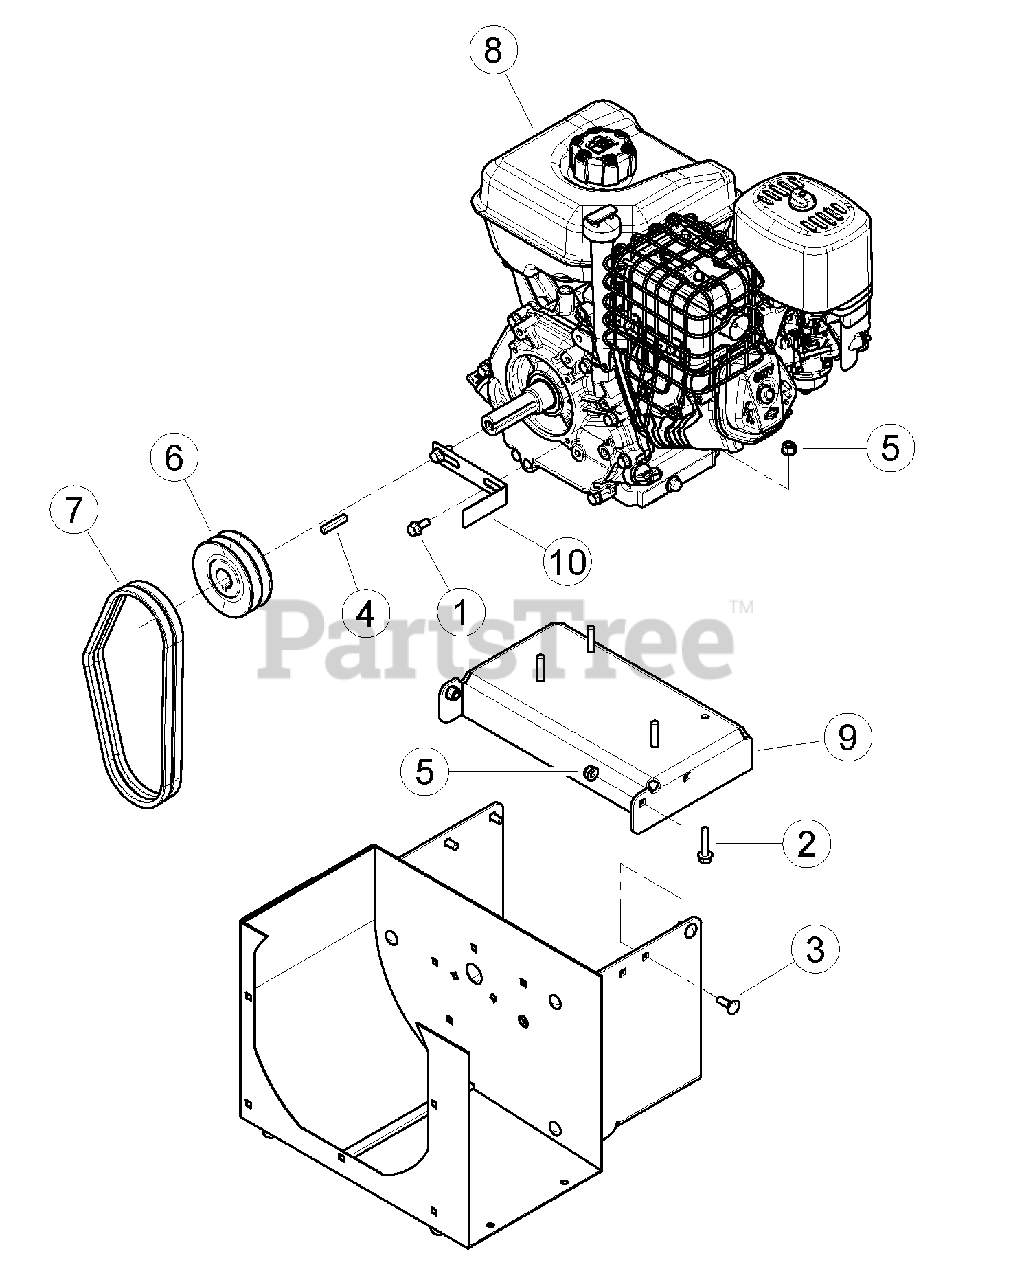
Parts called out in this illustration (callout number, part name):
1	BOLT, 5/16 X 3/4 SERRATED FLANGE NF
2	BOLT, 5/16 X 1-1/2 FLANGE NC
3	BOLT, 5/16 X 1" GR5 CRG ZP
4	KEY, 1/4 SQUARE X 1-1/2 LONG PLAIN
5	NUT, 5/16-18 NYLOCK-FLANGE
6	PULLEY, 4 X1 2A GROOVE
7	BELTS, HAH29.1 EL MATCHED SET
8	ENGINE, 420CC B&S HORIZONTAL
9	PLATE, ENGINE MOUNTING
10	GUIDE, BELT
